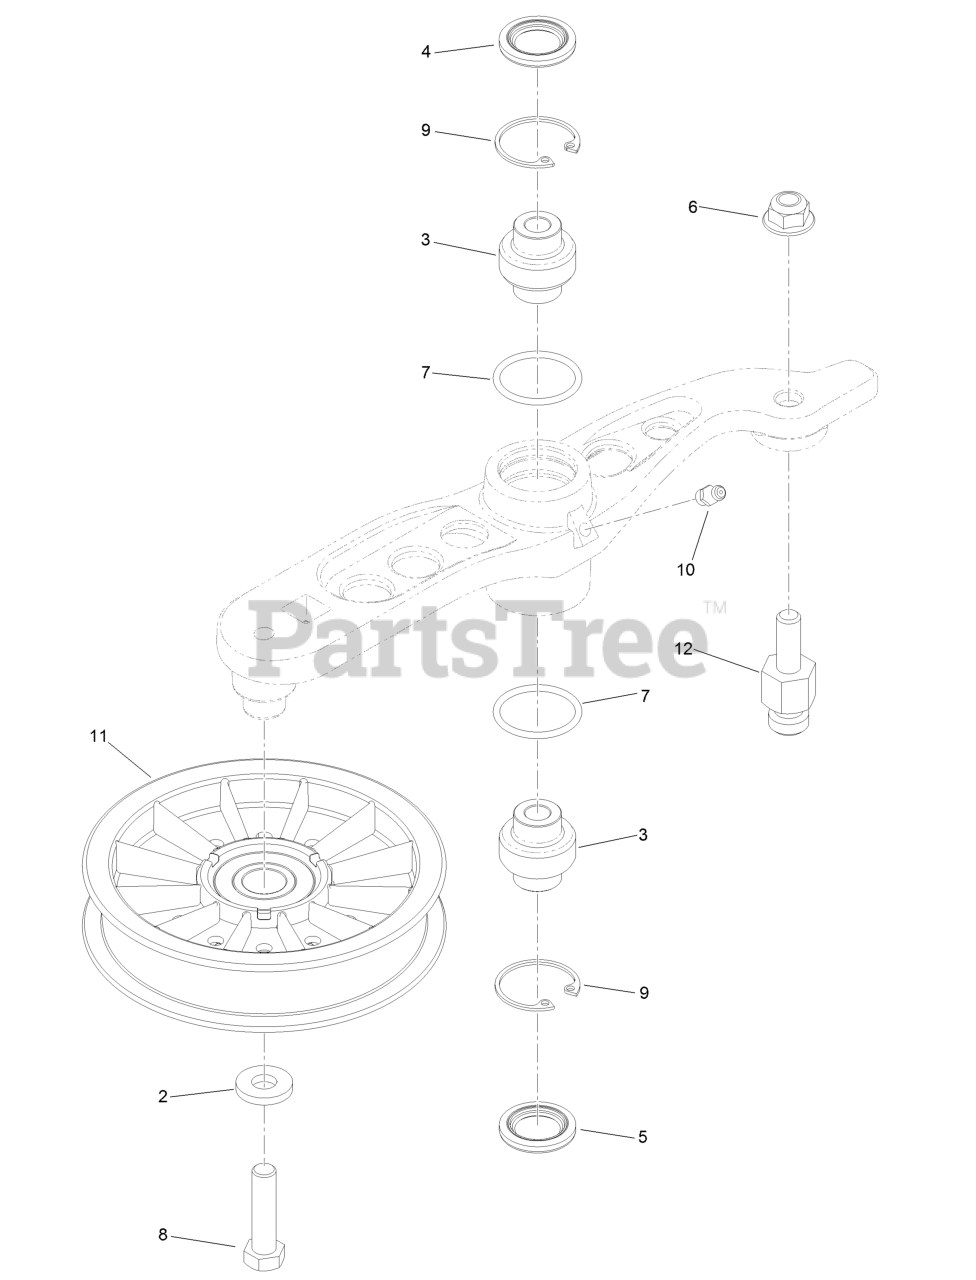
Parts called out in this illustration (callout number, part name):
3	Bearing-Spherical
4	Seal-Lip, Double
5	Seal-Single Lip
6	Nut-Nyloc 3/8-16 Flg
8	Screw-HH 3/8-16 X 1 1/2
9	Ring-Retaining
10	Zerk-1/4-28 Str
11	Pulley-Idler
12	Pin-Anchor, Spring
